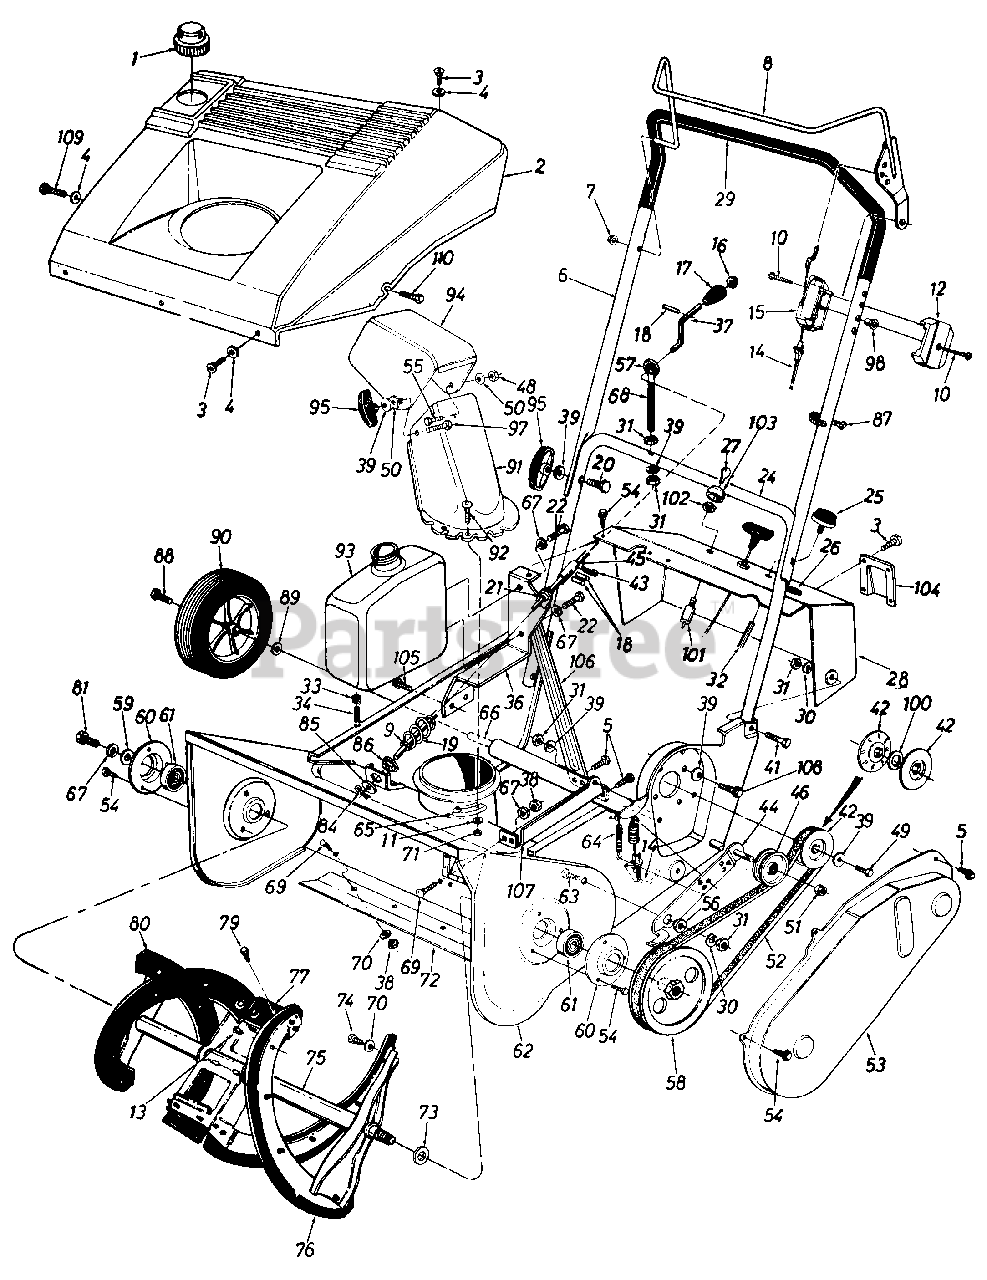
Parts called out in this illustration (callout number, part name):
1	Gas Tank Cap
2	Shroud
3	Hex B-Tap Scr. #10 x .5" Lg.
4	Fl-Wash. .203" I.D. x .41"
5	Hex L-Wash. Hd. AB-Tap 1/4 x .62" Lg.
8	Control Handle Ass'y. L.H.
9	Fl-Wash. .385" I.D. x .62"
10	Truss Mach Hi-B Tap Scr. Lg.
11	Fl-Wash. .281" I.D. x .5" O.D.
12	Control Panel Half
13	Pop Rivet .188" Dia.
14	Clutch Cable 35" Lg.
15	Control Panel Half
16	Push Cap 3/8" Rod
17	Knob 3/8" Dia. Hole
18	Roll Pin 118" Dia. x .63" Lg.
19	Lower Chute Crank Ass'y.
20	Curved Carriage Bolt 5/16-18 x 1.75" Lg.
21	Chute Crank Grommet
22	Hex Bolt 1/4-20 x .5" Lg.
26	Plastic Plug
30	L-Wash. 5/16" I.D.
31	Hex Nut 5/16-18 Thd.
32	Primer Hose 9" Lg.
33	Hose Clamp 1/2" O.D.
34	Gas Line 16" Lg.
36	Gas Tank Support Brkt.
38	Hex Jam Nut 1/4-20 Thd.
39	Saddle Wash. .32" I.D. x .937"
41	Hex Bolt 5/16-18 x 1.5" Lg.
42	3/8" "V"-Pulley Half .625" I.D. x 6.0" O.D.
43	Hairpin Clip 3/8" Dia.
46	Fl-Idler w/Flanges 2.12" O.D.
48	Hex L-Nut 5/16-18 Thd.
49	Hex Bolt 5/16-24 x .75" Lg.
50	Fl-Wash. .344" I.D. x 1.25"
51	Hex Patch L-Nut 3/8-24 Thd.
52	"V"-Belt
54	Hex B-Tap Scr. 1/4" x .38" Lg.
55	Carriage Bolt 5/16-18 x .75"
56	Shld. Spacer .50" Dia. x .27"
57	Plastic Bushing .38" I.D.
58	1/2" "V"-Pulley 1/2-20 L.H. x 6"
59	Fl-Wash. 1/4" I.D. x .93" O.D.
64	Extension Spring 1.12" Lg.
65	Chute Flange Keeper
66	Wheel Axle 20.6" Lg.
67	L-Wash. 114" I.D.
68	Eyebolt
69	Carriage Bolt 1/4-20 X .50"
70	Fl-Wash. .281" I.D. x .73"
71	Hex L-Nut 1/4-20 Thd.
72	Shave Plate
73	Fl-Wash. .510" I.D. x 1.0" O.D.
74	Hex Wash. B-Tap Scr. 1/4 x .62"
76	Rubber Spiral L.H.
77	Rubber Paddle
79	Hex Wash. B-Tap Scr. #10 x .62" Lg.
80	Rubber Spiral R.H.
81	Hex Wash. TT-Tap Cl-Scr. 1/4-20 x .75" Lg.
84	Cotter Pin 3/32" Dia. x .75"
85	Fl-Wash. .406" I.D. x 1.25"
86	Hex Bushing .385" I.D.
87	Cable Tie
88	Hex Tap Scr. 3/8-24 x .5" Lg.
89	Fl-Wash. .510" I.D. x .75"
90	7" Wheel & Tire Ass'y.
91	Lower Chute
92	Truss Mach. Scr. 1/4-20 x .75"
93	Fuel Tank Two Qt.
94	Upper Chute
95	Knob Handle Ass'y.
97	Carriage Bolt 5/16-18 x 1"
98	Control Disc Pin
100	Fl-Wash. .635" I.D. x .93" O.D.
101	Key Switch
102	Ignition Switch Nut 5/8-32 Thd.
103	Ignition Switch Cap
104	Choke Cover
105	Hex Wash. Hd. Tap Scr. 1/4-.5" Lg.
108	Hex Bolt 5/16-18 x 518" Lg.
109	Pan Hd. Tap Scr. #10 x 1.25"
110	Hex Wash. Hd. Tap Scr. 1/4-20
